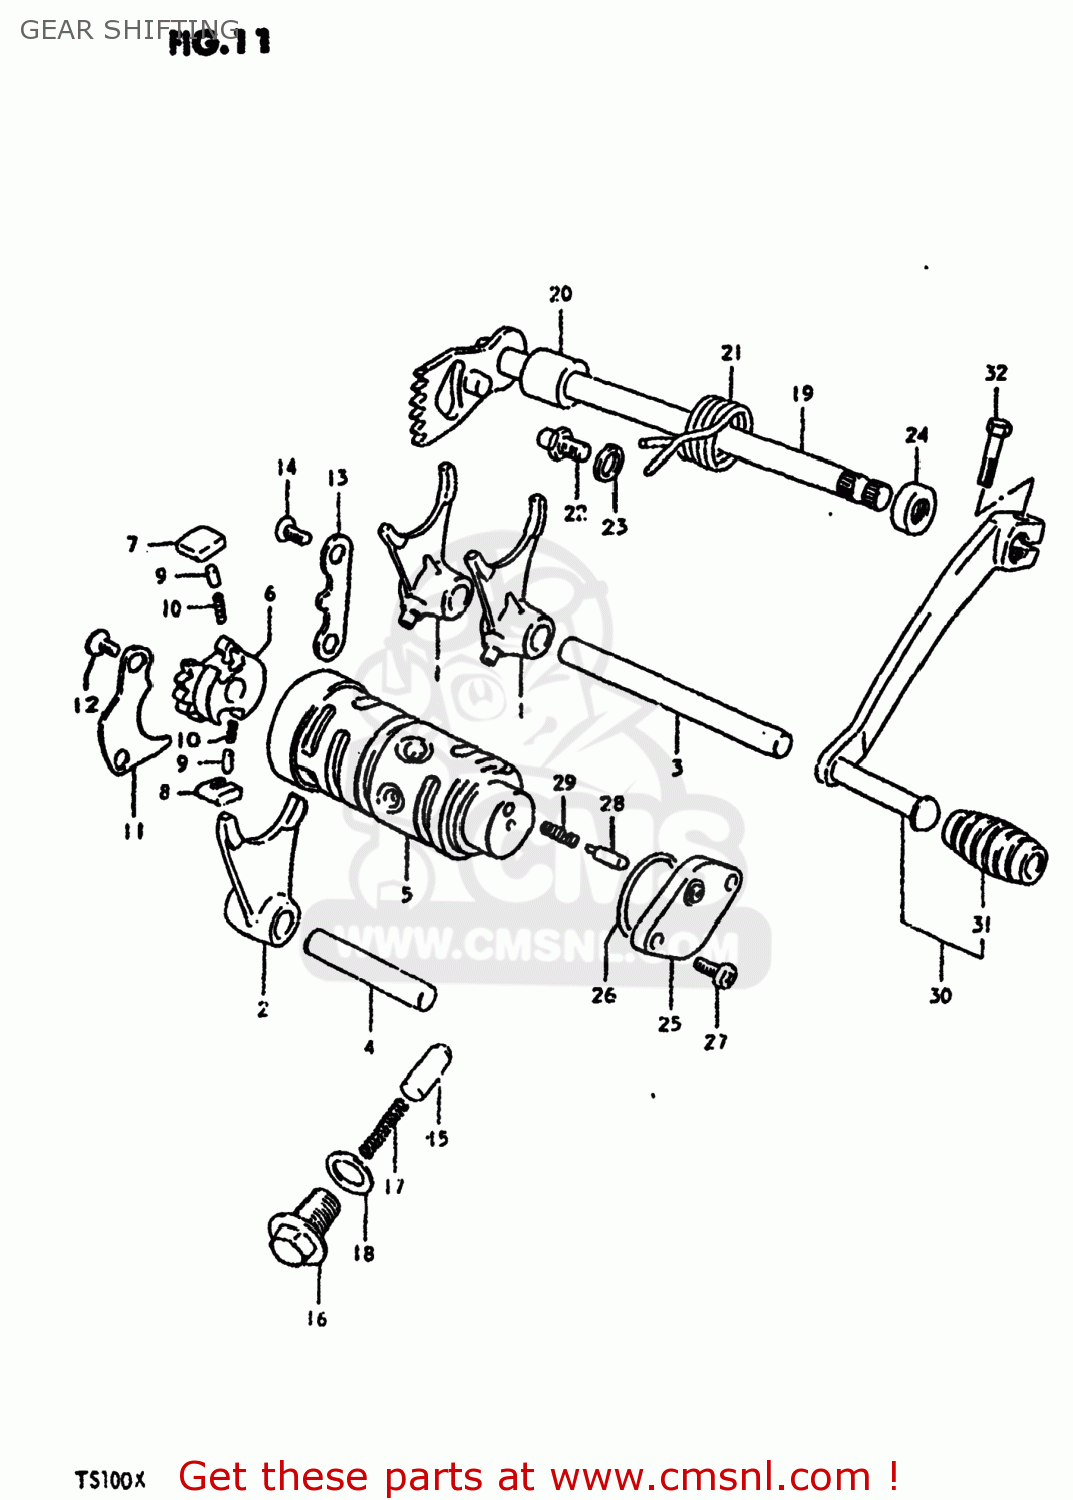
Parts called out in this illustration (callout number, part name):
1	FORK,GEAR SHIFT NO.1
2	FORK,GEAR SHIFT NO.2
3	SHAFT,GEAR SHIFT FORK
4	SHAFT,GEAR SHIFT FORK
5	CAM,GEAR SHIFT
6	RETAINER,GEAR SHIFT CAM
7	PAWL,GEAR SHIFT NO.1
8	PAWL,GEAR SHIFT NO.2
9	PIN(5X8)
10	SPRING
11	LIFTER,GEAR SHIFT PAWL
12	SCREW
13	GUIDE,GEAR SHIFTING CABLE
14	SCREW
15	STOPPER,GEAR SHIFTING
16	BOLT,GEAR SHAFT CAM STOPPER
17	SPRING
18	GASKET(14X19.2X2) (NAS)
19	SHAFT,GEAR SHIFT
20	SPACER(12X20X15.3)
21	SPRING
22	STOPPER,GEAR SHIFT CAM
23	WASHER
24	OIL SEAL
25	BODY,GEAR SHIFT SWITCH
26	O-RING (D:2.4 ID:26.2)
27	SCREW
28	PIN(5X15.5)
29	SPRING
30	LEVER ASSY,GEAR SHIFT
31	RUBBER,GEAR SHIFT PEDAL
32	BOLT
